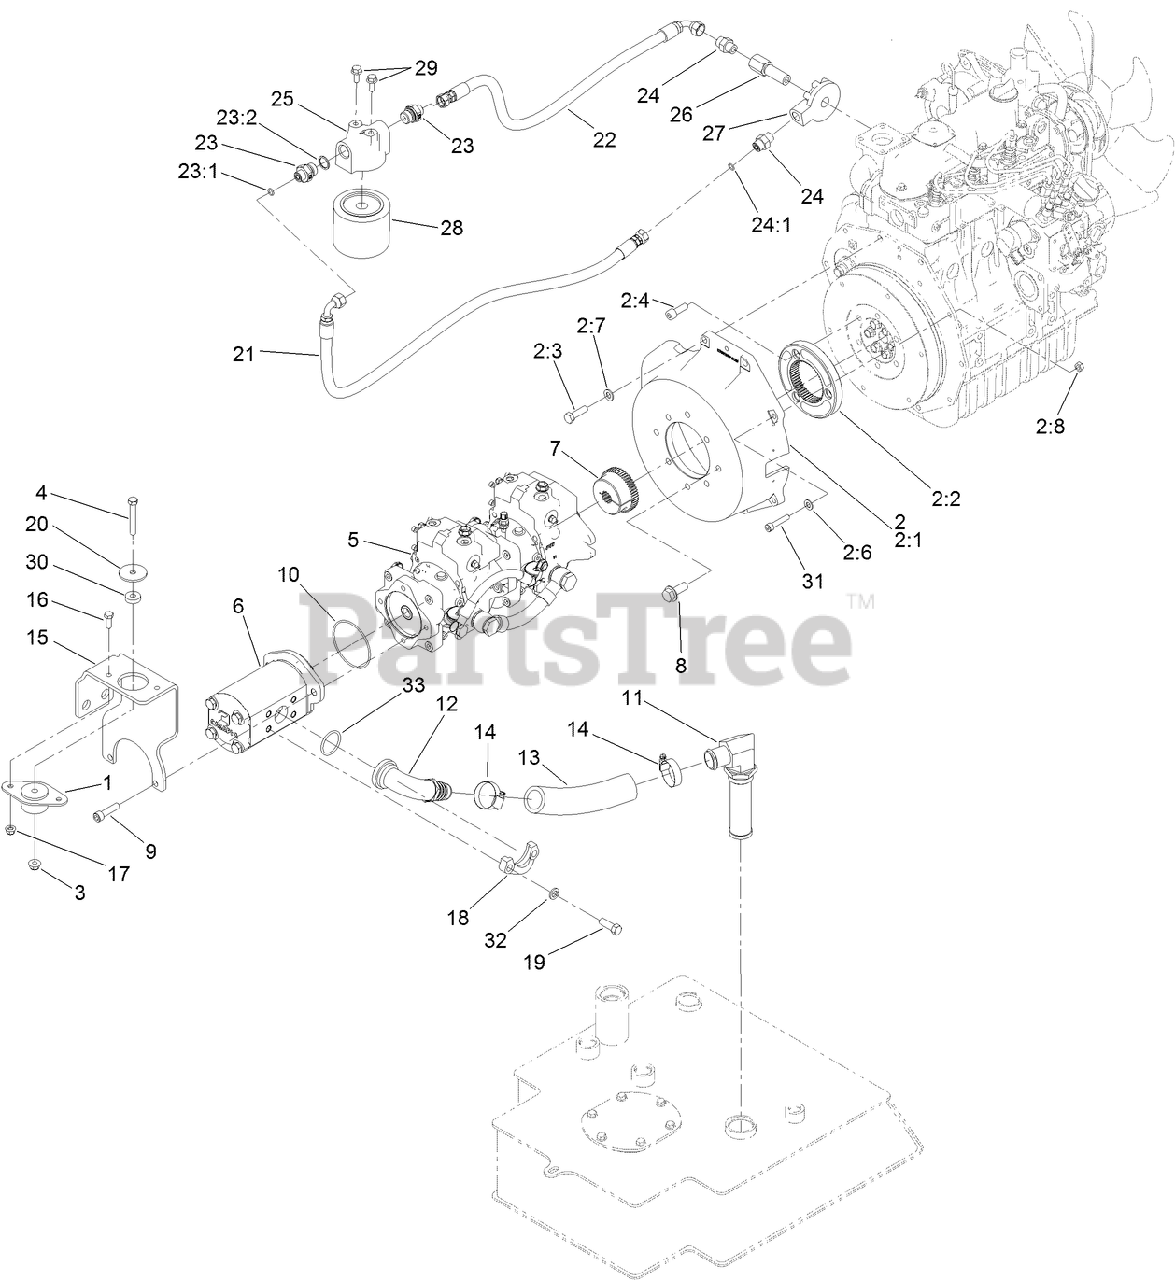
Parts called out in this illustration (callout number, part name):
1	MOUNT-ENGINE
2	MOUNT-PUMP
2:1	HOUSING-PUMP MOUNT
2:2	FLANGE-COUPLER
2:3	SCREW-HH
2:4	SCREW-HSH
2:6	WASHER-PLAIN
2:7	WASHER-FLAT
2:8	NUT-HEX
3	NUT-HF, NI
4	SCREW-HH
5	PUMP-TANDEM
6	PUMP-GEAR
7	HUB-PUMP
8	SCREW-HHF
9	SCREW-SH
10	O-RING
11	STRAINER-SUCTION
12	FITTING
13	HOSE-SUCTION
15	PLATE-SUPPORT, PUMP
16	SCREW-HH
17	NUT-HF, NI
18	FLANGE
19	SCREW-HH
20	WASHER-REBOUND
21	HOSE-HYD
22	HOSE-HYD
23	FITTING-HYD
23:1	O-RING
23:2	O-RING
24	FITTING-HYD
24:1	O-RING
25	BASE-FILTER
26	PIPE-JOINT
27	BASE-FILTER
28	FILTER-OIL
29	SCREW-HHF
30	SPACER
31	SCREW-HSH
32	WASHER-LOCK
33	O-RING
